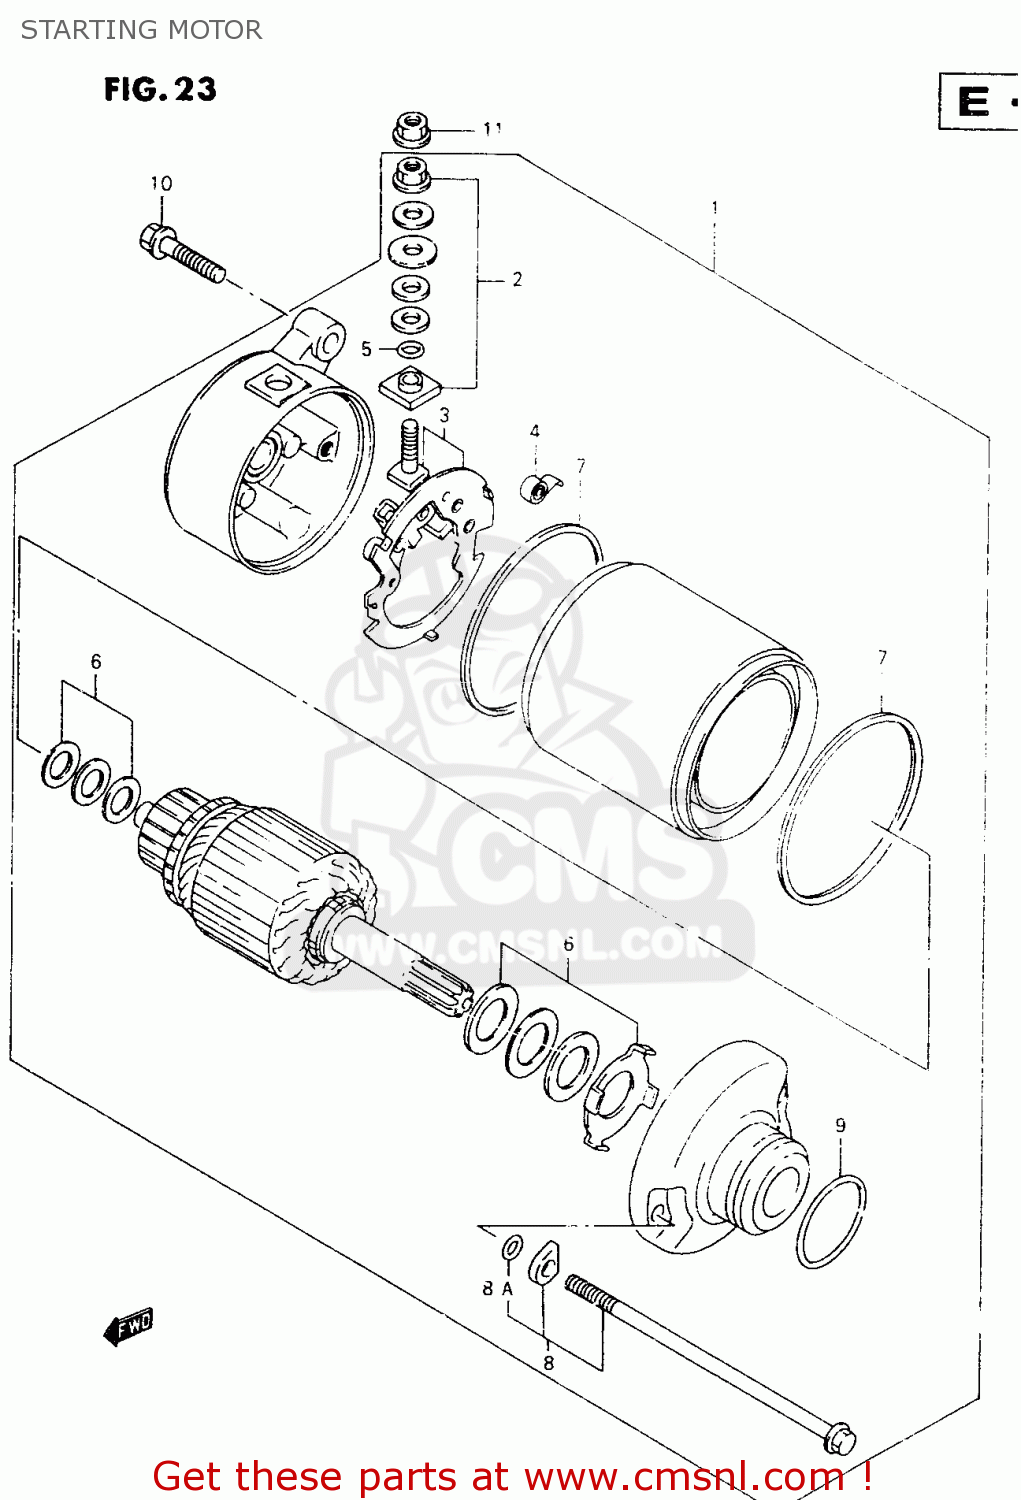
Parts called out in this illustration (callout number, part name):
1	MOTOR ASSY,STARTING
2	TERMINAL SET,BRUSH,PLUS
3	HOLDER SET,BRUSH
4	SPRING,BRUSH
5	O RING
6	SHIM SET,STARTING MOTOR
7	O RING
8	BOLT SET,STARTING MOTOR
8A	O RING
9	O RING(D:3,ID:24.5)
10	BOLT
11	NUT
